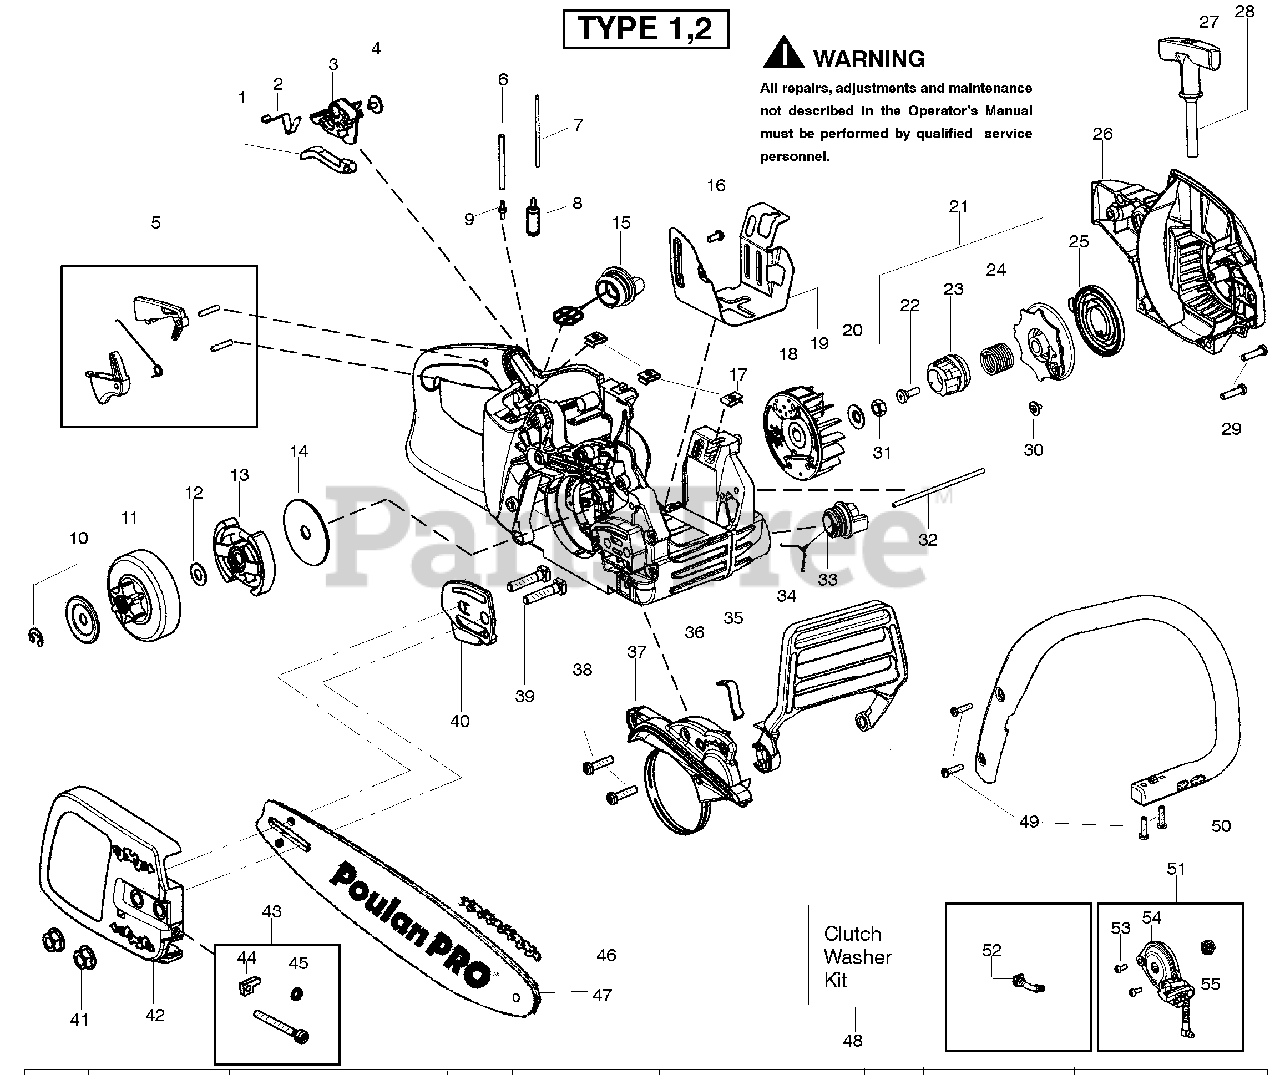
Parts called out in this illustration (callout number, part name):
2	Spring-Ign. Switch
3	Lever-Ign. Switch
5	Kit-Trigger/Lockout
6	Kit-Fuel Line (Large)
7	Kit-Fuel Line (Small)
8	Assy-Fuel Pick Up
9	Fitting-Fuel line
10	Kit-Clutch Washer
11	Assy-Clutch Drum 3/8"
12	Kit-Clutch Washer
14	Washer-Large Clutch
15	Assy-Fuel Cap w/ret
17	Nut-"U" type speed
18	Assy-Flywheel
20	Washer-Flywheel
21	Kit-EPS Starter Pulley
22	Screw-Shoulder
25	Spring-Starter
27	Handle-Starter
32	Assy-Oil Vent
33	Assy-Oil Cap w/ret.
34	Handguard
35	Spring-Handguard
36	Assy-Chassis
37	Kit-Chainbrake
42	Assy-Clutch Cover
43	Kit-Bar Adjust
44	Pin-Bar Adjust
45	Retainer-Bar Adjust
46	Accy-18" Chain
48	Kit-Clutch Washer
51	Kit-Oil Pump
52	Assy-Oil Pick Up
54	Assy-Oil Pump
